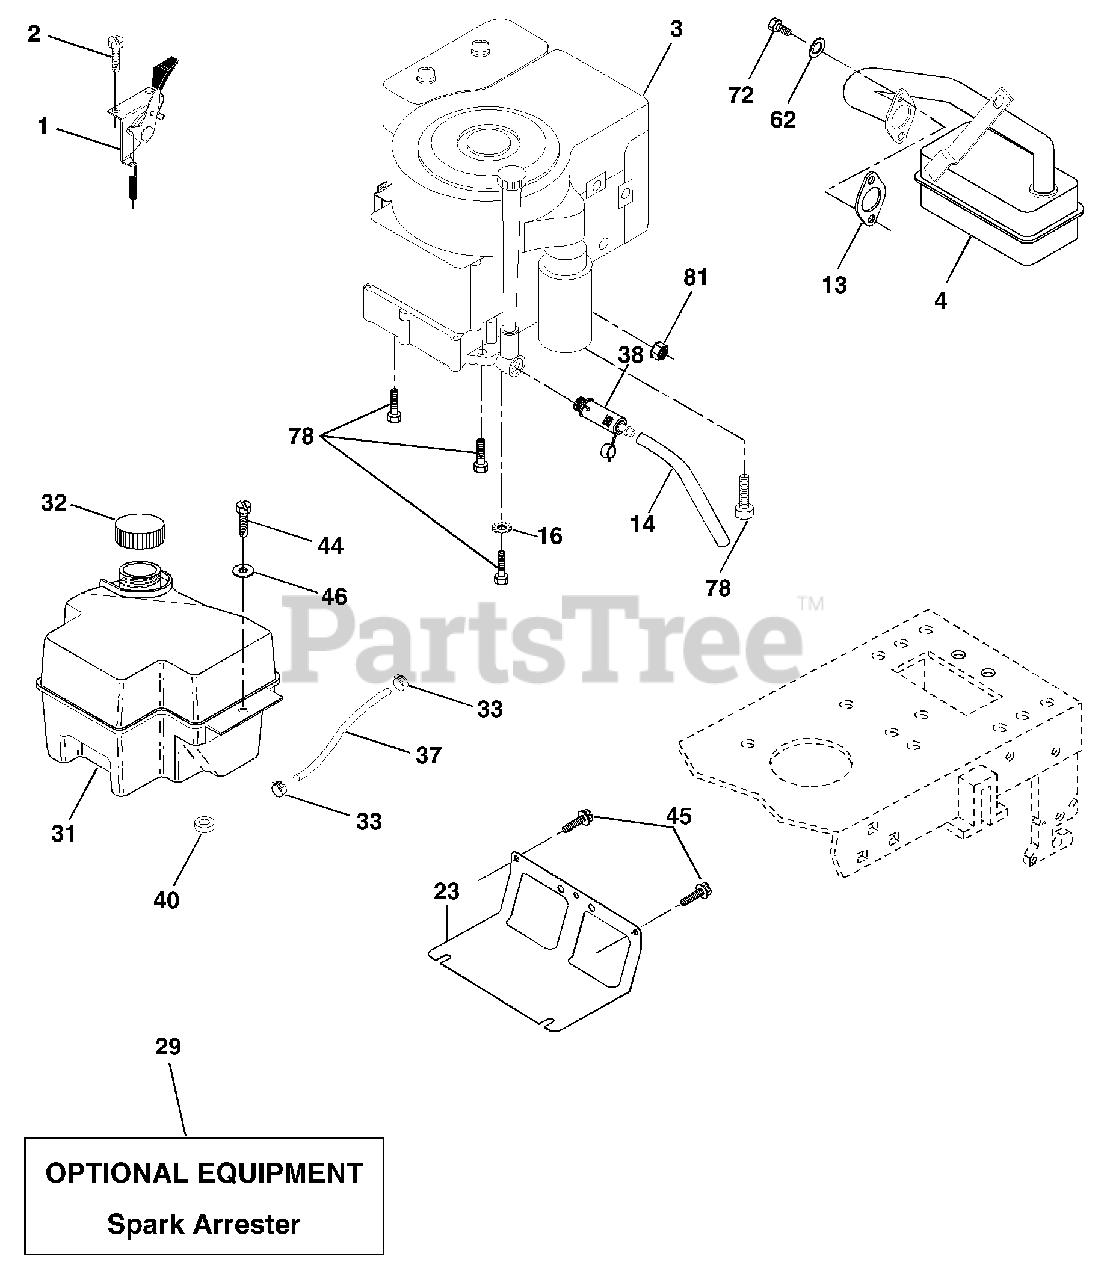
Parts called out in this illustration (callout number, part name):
1	Control Th/ch Flag Dom.
2	Screw Hex Thd Cut 1/4-20x5/8 T
13	Gasket
14	Tube Drain Oil Easy
16	Washer Lock Ext Tooth 3/8
23	Shield BRN/DBR Guard
29	Kit Spark Arrestor (Flat Scrn)
31	Tank Fuel
32	Cap Asm Fuel W/sym Vented
33	Clamp Hose Black
37	Line Fuel
38	Plug Drain Oil Easy
40	Bushing Snap Nyl Black Fuel Line
44	Screw Hex Wsh Thdrol 1/4-20 x 3/4
45	Screw Hex Wsh Thdrol 3/8-16 x 3/4
46	Washer 9/32 x 7/8 x 16 Ga.
62	Washer Lock Hvy Hlcl Spr. 5/16
72	Screw Hex Hd Cap 5/16-18 x 3/4
78	Screw 3/8-16 x 1-1/4
81	Nut Keps Hex 1/4-20 Unc
